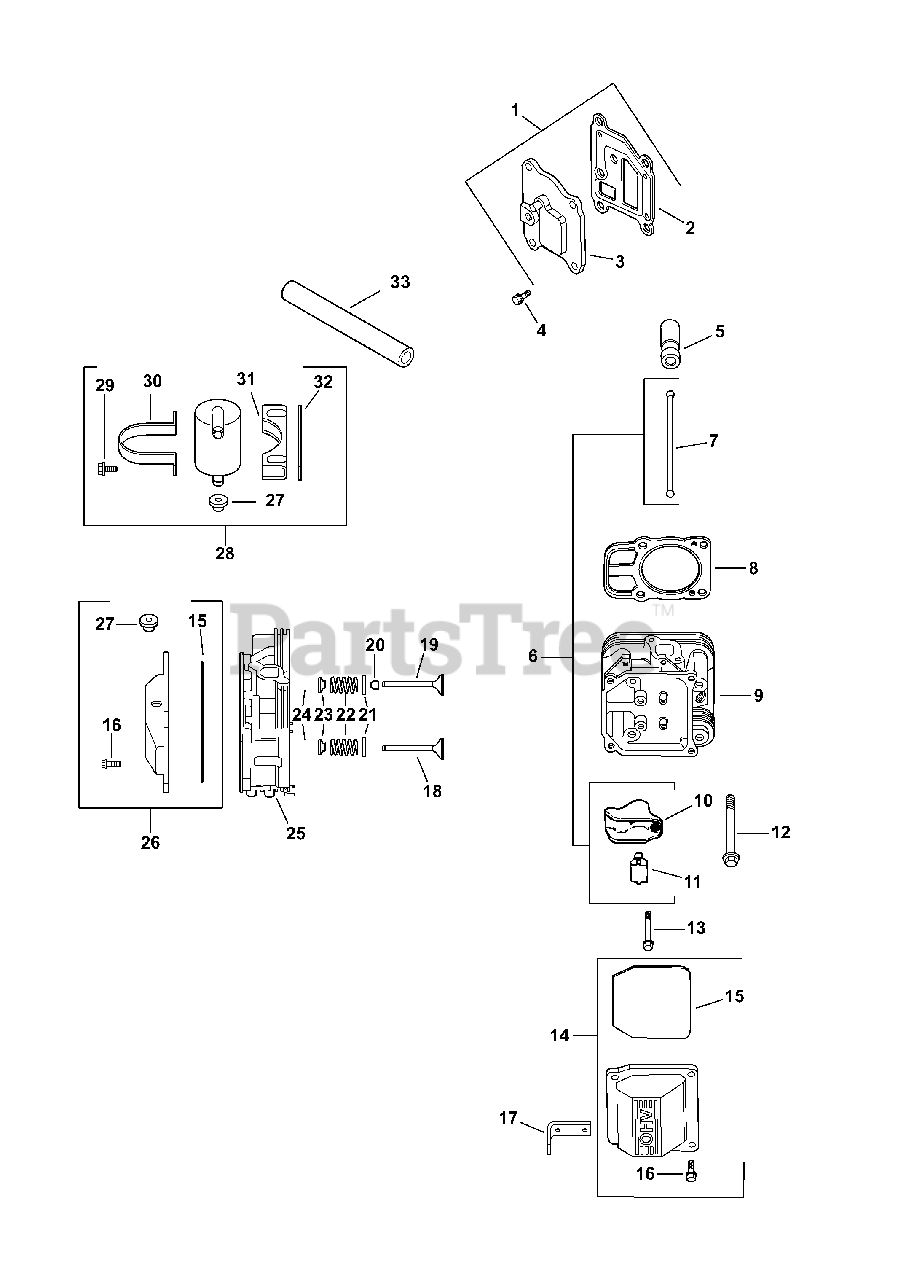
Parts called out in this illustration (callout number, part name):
1	Kit, Breather Cover W/Gasket (Includes 2-3)
2	Gasket, Breather
3	Cover, Breather
4	Screw, Flg Thd Frm M6x1.0x20
5	Kit, Hydraulic Valve Lifter (Includes Lubricant)
6	Kit, Valve Train (Includes 7, 10, 11)
8	Kit, Gasket Cylinder Head (Inc. 13 qty. 4)
9	Kit, Head #2 (Includes Kh-25-072-04)
11	Pivot, Rocker Arm
12	Screw, Flg M10x1.5x90
13	Screw, Flg M6x1.0x34
14	Kit, Valve Cover-Plain (Includes 15,16)
15	O-Ring, Valve Cover
16	Screw, Flg M6x1.0x30
17	Strap, Lifting
18	Valve, Exhaust (Std)
18	Valve, Exhaust (.25)
19	Valve, Intake (Std)
19	Valve, Intake (.25)
20	Seal, Valve Stem
21	Retainer, Spring
22	Spring, Valve
23	Cap, Valve Spring
24	Kit, Retainer
25	Kit, Head #1 (Includes Kh-25-072-04)
26	Kit, Valve Cover Breather (Includes 15, 16, 27)
27	Grommet, Rubber
28	Kit, Breather Seperator (Includes 27)
29	Screw, Flg Thd Frm M5x0.8x16
30	Breather Strap
31	Breather Bracket
33	Hose, Breather
